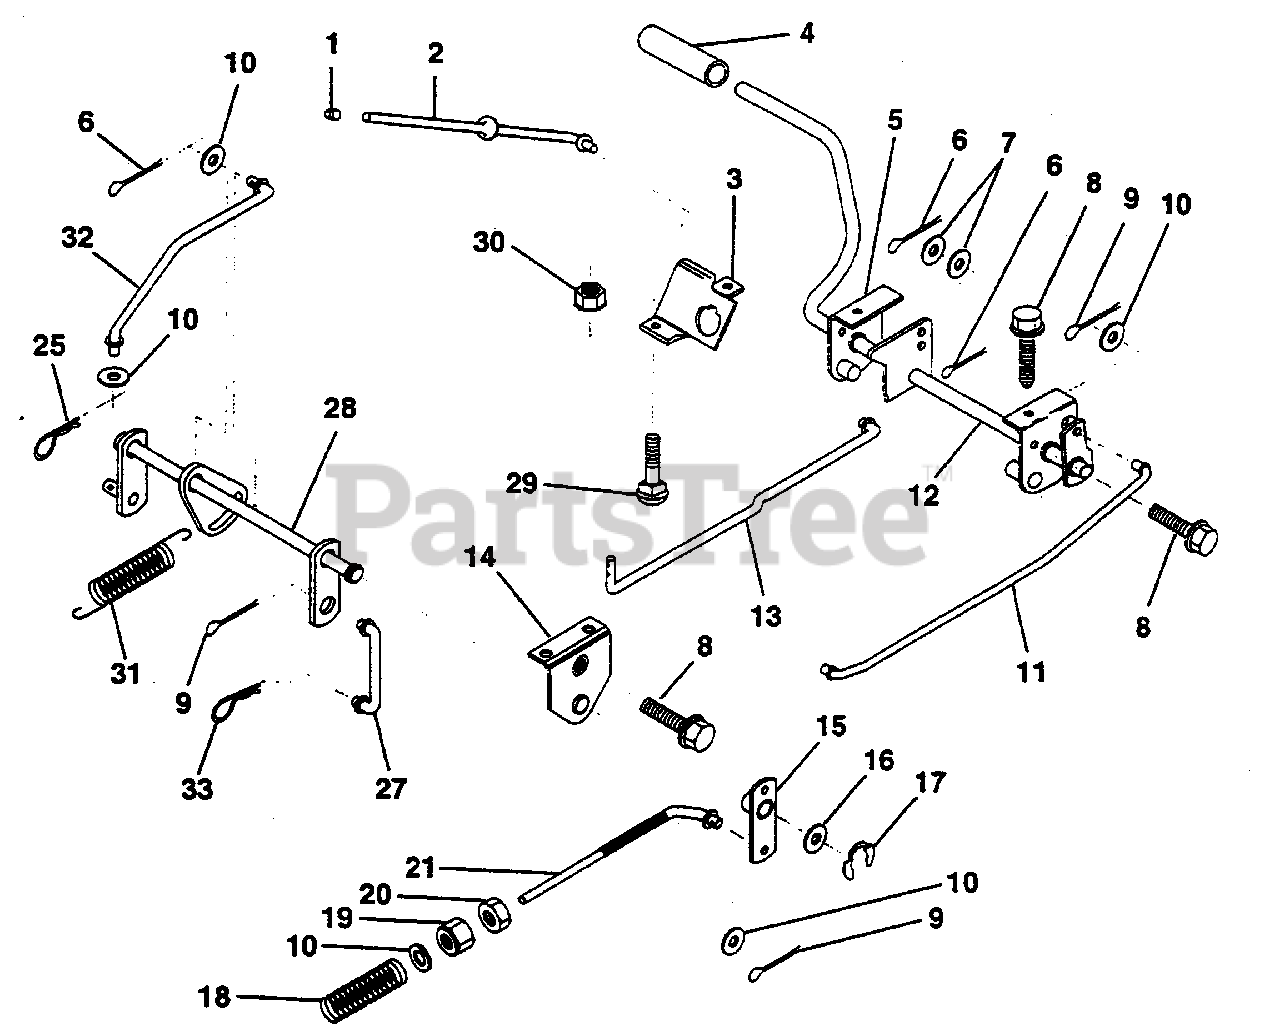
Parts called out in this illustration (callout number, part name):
2	Rod, Parking Brake
3	Bracket, Parking Brake
4	Cover, Pedal
5	Bracket, Clutch/Brake Pedal, L.H.
6	Pin, Cotter 3/32 x 3/4
7	Washer 13/32 x 5/8 x 16 Gauge
8	Screw, Hex Head, Thd., Roll. 5/16-18 x 1/2
9	Pin, Cotter 1/8 x 3/4
10	Washer 13/32 x 13/16 x 16 Gauge
11	Rod, Brake, Front
12	Assembly, Clutch/Brake Pedal
13	Rod, Clutch
14	Bracket, Lift Shaft
15	Assembly, Brake, Pivot, Arm
16	Washer 25/32 x 1-1/8 x 16 Gauge
18	Spring, Brake Rod
19	Nut, Hex, Jam 3/8-16 UNC
20	Nut, Crownlock 3/8-16 UNC
21	Rod, Brake, Rear
25	Spring, Retainer
27	Link, Lift, Rear
28	Assembly, Rear Mower Lift
29	Bolt, Carriage 5/16-18 UNC x 3/4
30	Nut, Hex, Keps 5/16-16 UNC
31	Spring, Counterbalance
32	Link, Lift Lever
33	Retainer Spring
